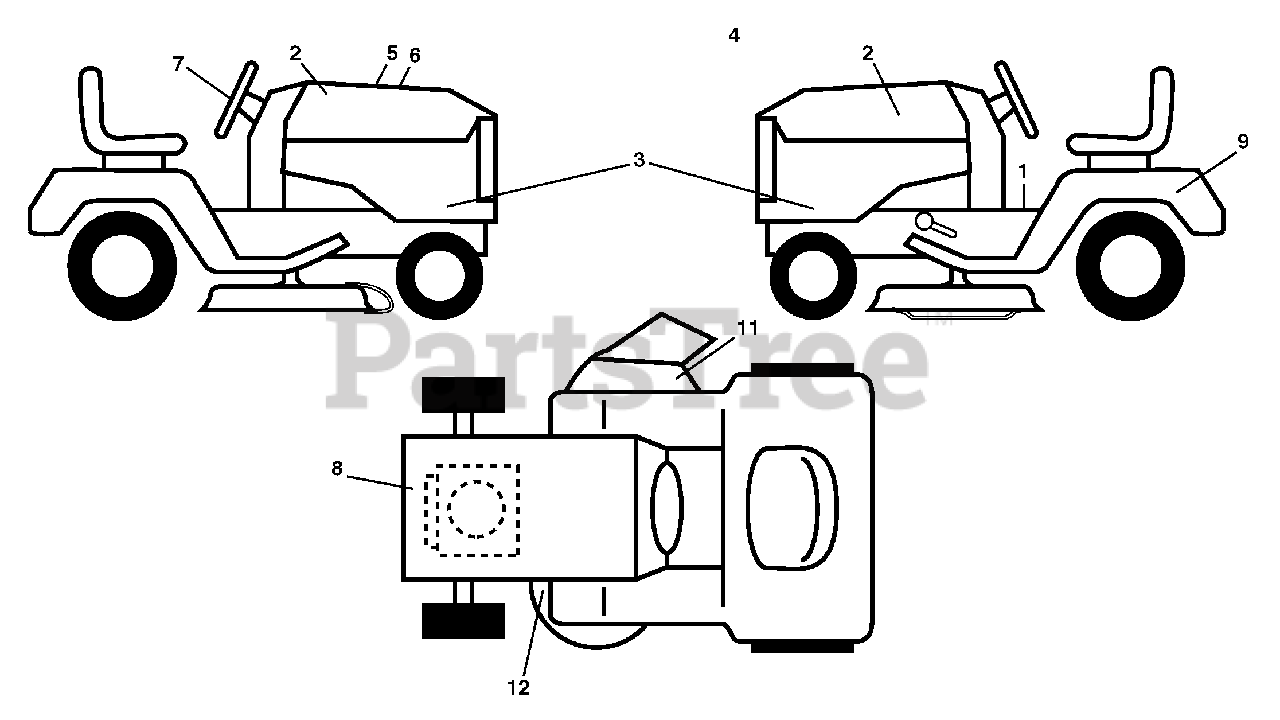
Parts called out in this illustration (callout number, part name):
1	Decal, Operators
2	Decal, Hood
3	Decal, Hood Panel SD
4	Decal, Hood Top Insert
5	Decal, Customer Respons.
6	Decal, Replacement
7	Decal, Steering Wheel
8	Decal, Eng. HP
9	Decal, Battery Dnge/Poi
11	Decal, Warning
12	Decal, Mower V-Belt Schematic
